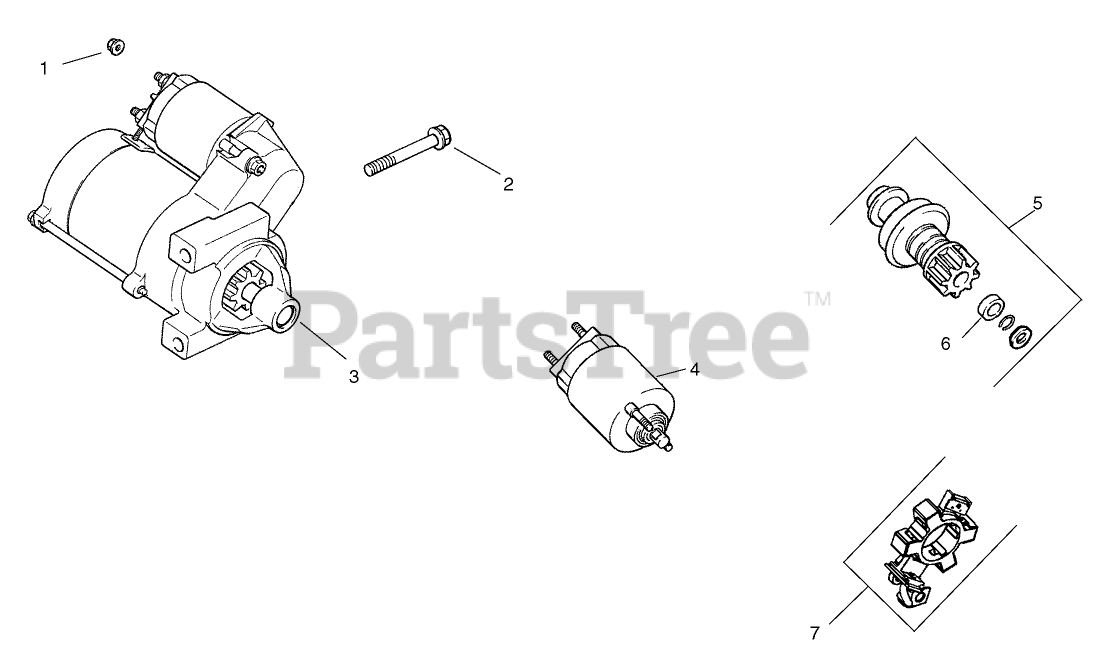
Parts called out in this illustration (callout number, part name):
1	NUT-FLANGE (M8X1.25)
2	SCREW-FLG (M8X1.25X80)
3	Starter, solenoid shift assembly (Includes 4-7)
4	Solenoid Kit
5	Kit, pinion drive (Includes 6)
6	RING-RETAINING
7	BRUSH HOLDER KIT
